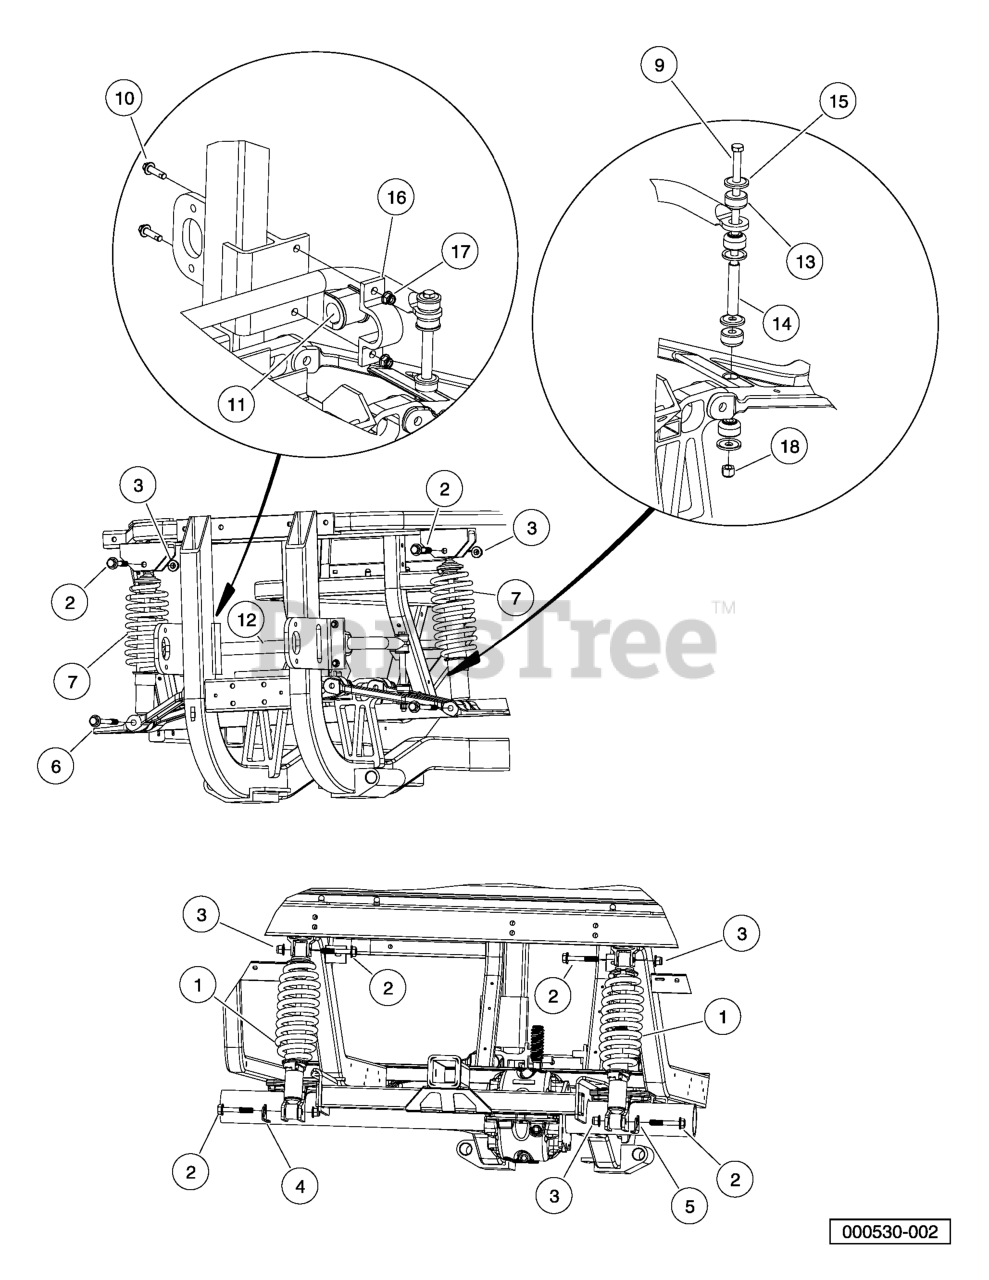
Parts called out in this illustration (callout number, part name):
1	SHOCK, COIL OVER, REAR HD
2	BOLT, FLG, M12X1.75X70
3	NUT FLG, M12X1.75, NYLON GR 10
4	BRKT, LINE, HYD, SHK MNT, DRV
5	BRKT, LINE, HYD, SHK MNT, PASS
6	BOLT FLG, M12X1.75X100, PATCH
7	ASM, COIL & SHOCK, FRT
8	Instl, Bar, Antisway, Wide Frt
9	SCREW, 3/8-16 X 7.00 HEX CAP
10	BOLT - FLANGED HD, M8 X 30.0
11	BUSHING, ANTI-SWAY BAR, 1-1/8
12	BAR, SWAY, FORMED
13	BUSHING, LINK
14	SLEEVE, LINK
15	WASHER, CUP, BUSHING
16	BRACKET, ANTI-SWAY BAR
17	LOCK NUT, FLG M8 X 1.25 NYLON
18	LOCKNUT, 3/8-16 HEX
